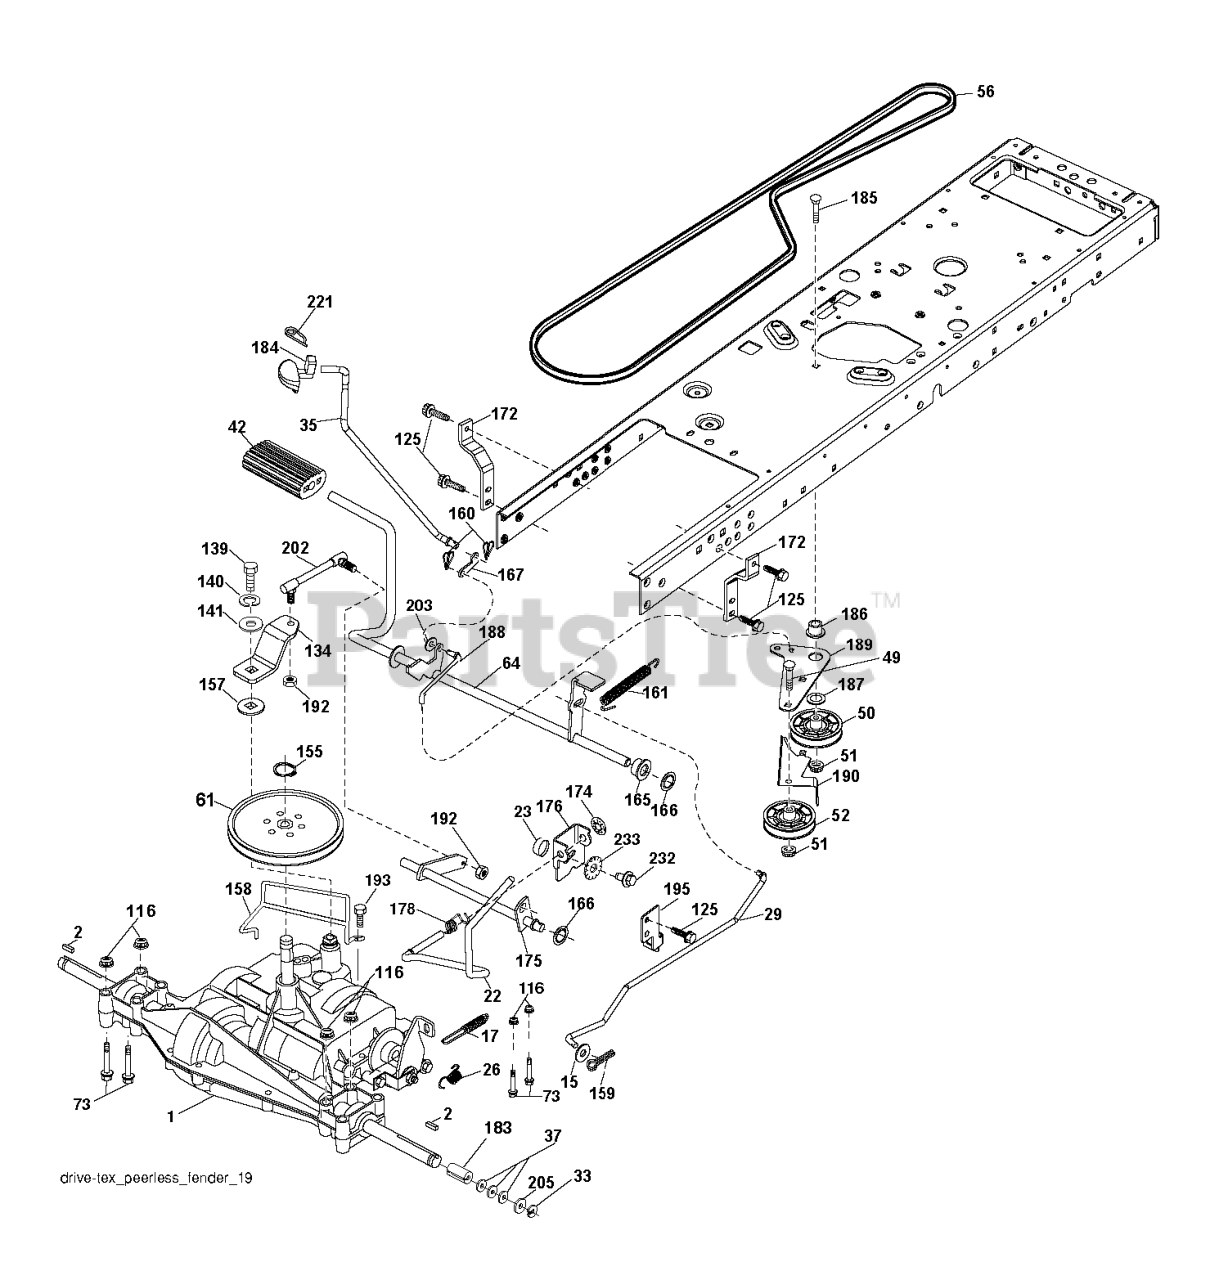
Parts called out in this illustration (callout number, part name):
2	SQUARE KEY
15	WASHER
17	SPRING.BRAKE.PEERLESS.TEX
22	ROD.SHIFT.FENDER.TLT.2006
23	KNOB.DUCKHEAD.1/2
26	SPRING.BRAKE.RTN.GR.DR
29	ROD.BRAKE.PEERLESS
35	ROD.CNTRL.PARK.PREDATOR.LT.TEX
42	PEDAL COVER T
50	IDLER.FLAT.910.OFFSET
51	NUT LOCK FLG 3/8-16 UNC
52	IDLER.V-GROOVE.910.OFFSET
56	V-BELT.TRACTOR.DRIVE.P
61	PULLEY TRANS
64	SHAFT.ASM.PEDAL.BRAKE.
73	BOLT HEX 5/16-18 GR 5
116	NUT LOCK HEX FLANGE 5/16-18
125	SCREW
139	BOLT 1/4-28X3/4
140	LOCKWASHER
155	RETAINING RING LT
157	WASH-SHFT PLT LT
158	KEEPER.PMS.18/20.D4365
159	COTTER PIN
160	RETAINER CLIP
161	SPRING, RETURN LT
165	BUSHING.SHAFT.BRAKE.HAND
166	NUT.PUSH.625.2006
167	LATCH.BRAKE.SPRING
172	STRAP.TRQ.LH.GEAR.DRIV
174	NUT.PUSH.500.2006
175	SHAFT ASM SHIFT
176	ARM.CLEVIS.ROD.SHIFT
178	SPRING.SHIFT.GT2006
183	SPACER AXLE
184	HANDLE PARKING BRAKE
186	SPACER.RETAINER
187	WASHER 12/32X2X10GA
188	RP.LINK.CLUTCH.GROUND.DRIVE
189	BELLCRANK.GROUND.DRIVE.TEX.
190	KEEPER.BELLCRANK.DRIVE
192	NUT LOCK CENTER 1/4 -28 FNTHD
193	SCREW 5/16"
195	BRKT.ROD.BRAKE.PEERLES
202	LINK.SHIFT.PMST.18" (SPG1286)
203	WASHER
221	RETAINER.SPRING.CLIP.H
232	BOLT FIN HEX 7/16-14 X 1
233	WASHER SERRATED
